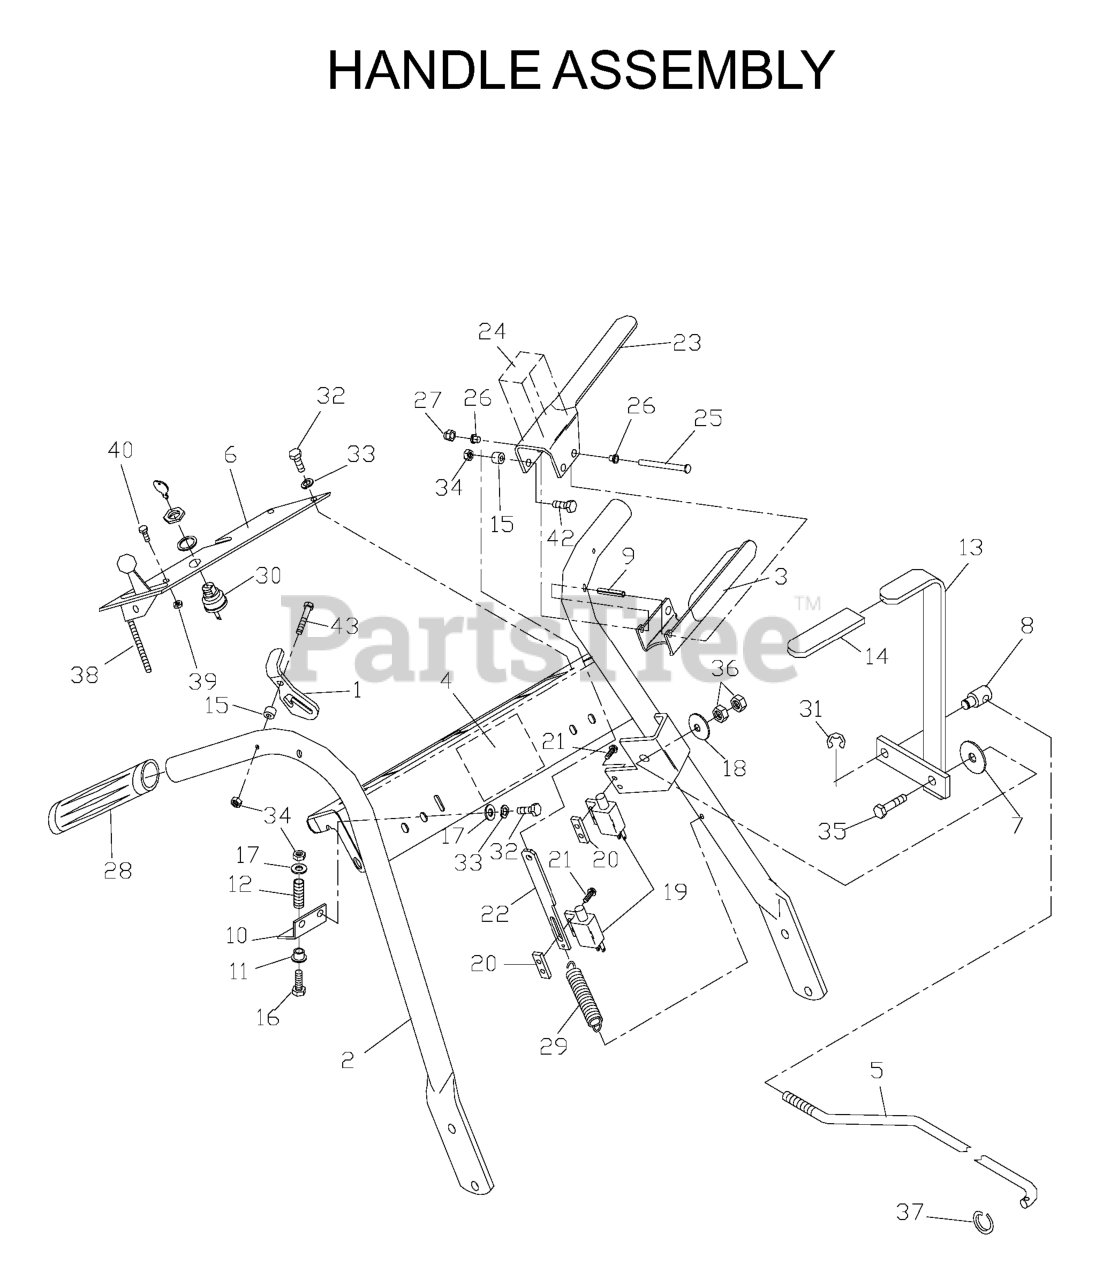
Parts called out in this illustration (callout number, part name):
1	THUMB LATCH RT.
2	HANDLE W/DECAL
3	CONTROL LEVER LT
4	DECAL, WARNING
5	BLADE LINK
6	ACCESS PLATE
7	WASHER, FRICTION
10	DETENT WLDMT
11	BUSHING, FLANGE
13	BLADE LEVER WLDMT
16	BOLT 1/4C X 1 3/4
17	WASHER 1/4 SAE
18	CONE WASHER
20	TAPPED PLATE
21	SCREW #10-24 X 5/8
22	LINKAGE, O P
23	LEVER OPC W/GRIP
24	DECAL, THUMB LATCH
25	PIN CLEVIS
28	GRIP HANDLE
30	KEY SWITCH, COMPLETE
31	E RING 3/8"
32	HCS 1/4C X 3/4
33	LOCKWASHER 1/4"
34	NUT 1/4C CENTERLOCK
35	HCS 3/8C X 1 1/2
36	NUT 3/8C CENTERBLOCK
38	THROTTLE CABLE (14 KAW.)
39	NUT 10-24 NYLOC
40	HCS #10-24 X 1/2
41	DNB DECAL,OPERATION
42	HCS 1/4 X 1
43	HCS 1/4C X 2
539101220	CABLE, THROTTLE (17 KAW.)
539102983	THUMB LATCH LT.
539102991	CONTROL LEVER RT
